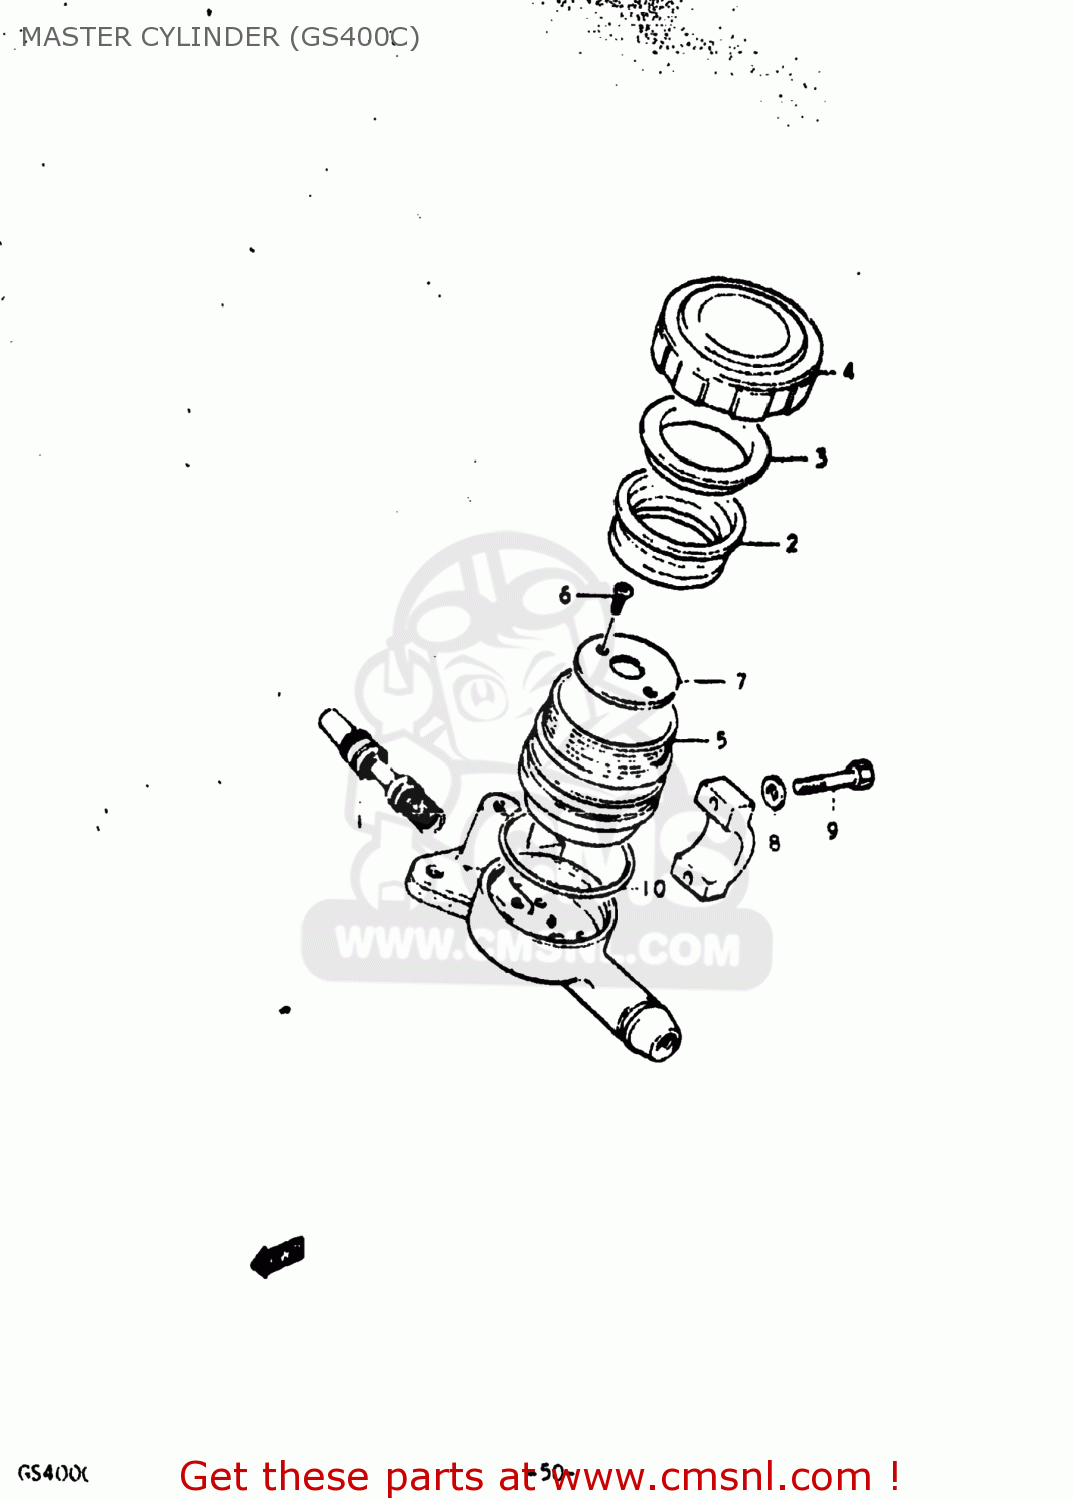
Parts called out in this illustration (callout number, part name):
1	CYLINDER ASSEMBLY,FRONT MASTER
2	DIAPHRAGM,MASTER CYLINDER
3	PLATE,DIAPHRAGM
4	CAP
5	RESERVOIR
6	SCREW
7	PLATE
8	WASHER
9	BOLT
10	O RING
